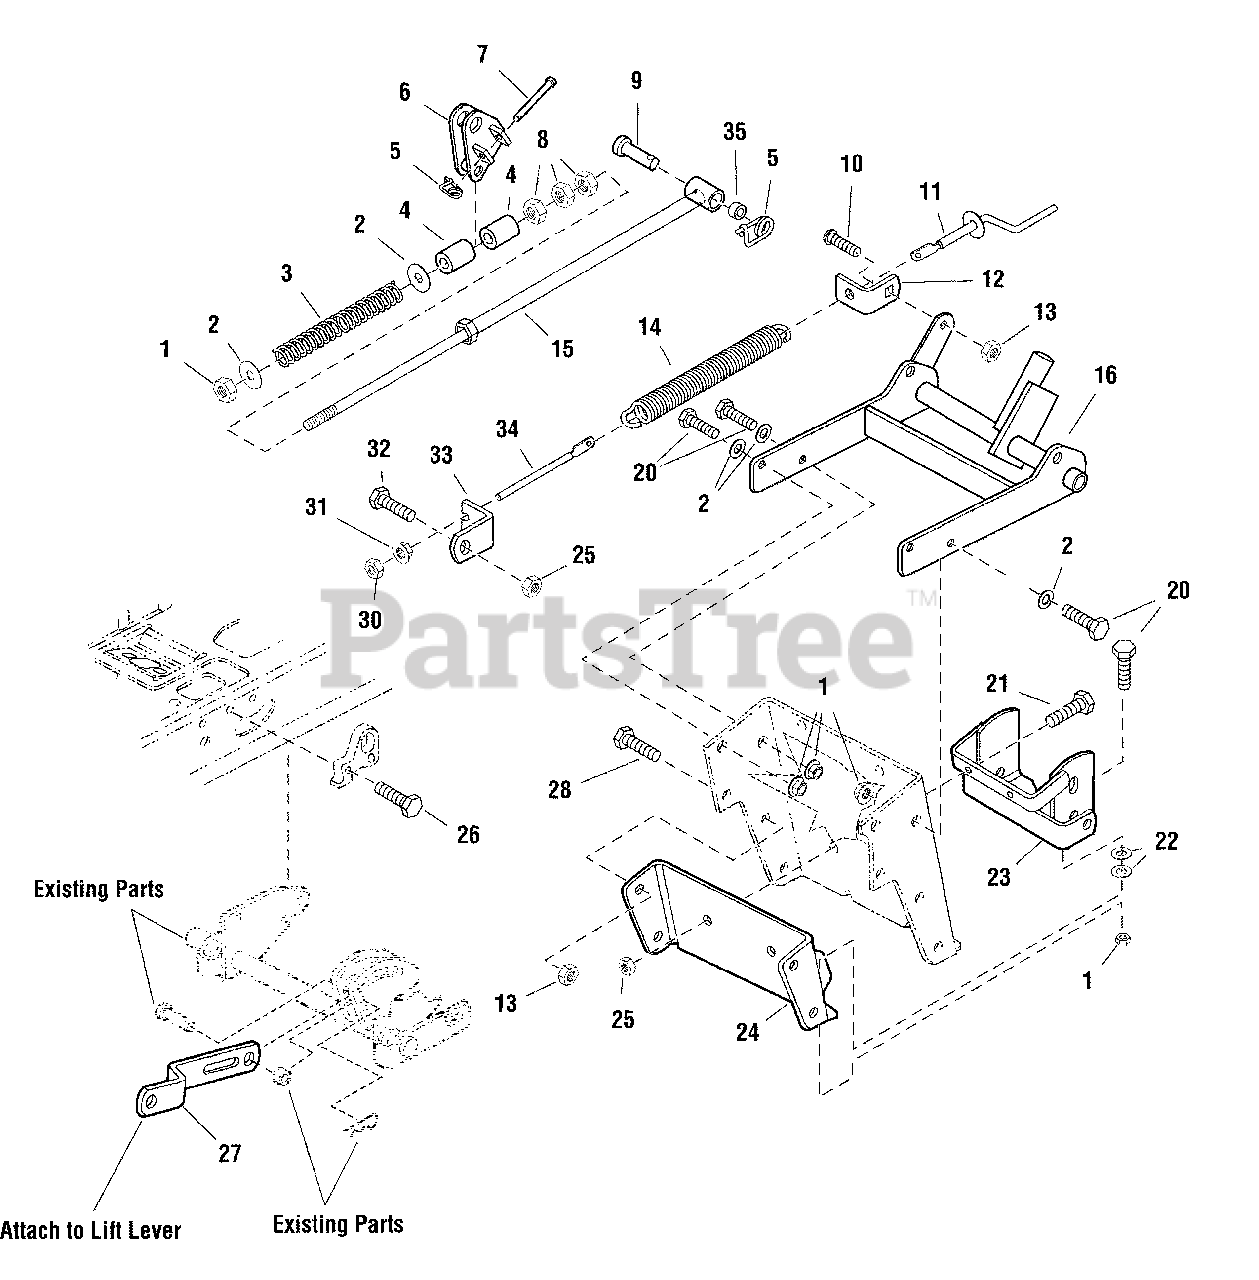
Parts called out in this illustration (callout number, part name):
1	NUT, Hex Lock ESNA, 1/2-13
2	WASHER, 1/2
3	SPRING, Compression
4	SPACER, .52 x .738 x 1.27
5	RETAINER, Pin
6	LIFT LEVER ASSEMBLY
7	PIN, Round Head Drilled, 3/8 x 2-3/8
8	NUT, Hex, 1/2-13
9	PIN, Yoke, Drilled, 5/8 x 1-13/16
10	CARRIAGE BOLT, 3/8-16 x 1
11	CRANK ASSEMBLY
12	CRANK BRACKET
13	NUT, Hex Lock ESNA, 3/8-16
14	SPRING, Extension
15	LIFT ROD ASSEMBLY
16	HITCH ASSEMBLY
20	CAPSCREW, Hex Head, 1/2-13 x 1-1/2
21	CAPSCREW, Hex Head, 1/2-13 x 1-1/4
22	WASHER, 1/2
23	HITCH ASSEMBLY BRACKET
24	HITCH SUPPORT
25	NUT, Hex Lock ESNA, 5/16-18
26	CAPSCREW, Hex Head, 5/16-18 x 1, G8
27	BAR, Lift Link
28	CAPSCREW, Hex Head, 3/8-16 x 1
30	NUT, Hex Centerlock Jam, 1/2-13
31	NUT, Hex Flange, 1/2-13
32	CAPSCREW, Hex Hed, 5/16-18 x 1
33	SPRING ANCHOR BRACKET
34	ROD, Threaded
35	SPACER, 1/2
